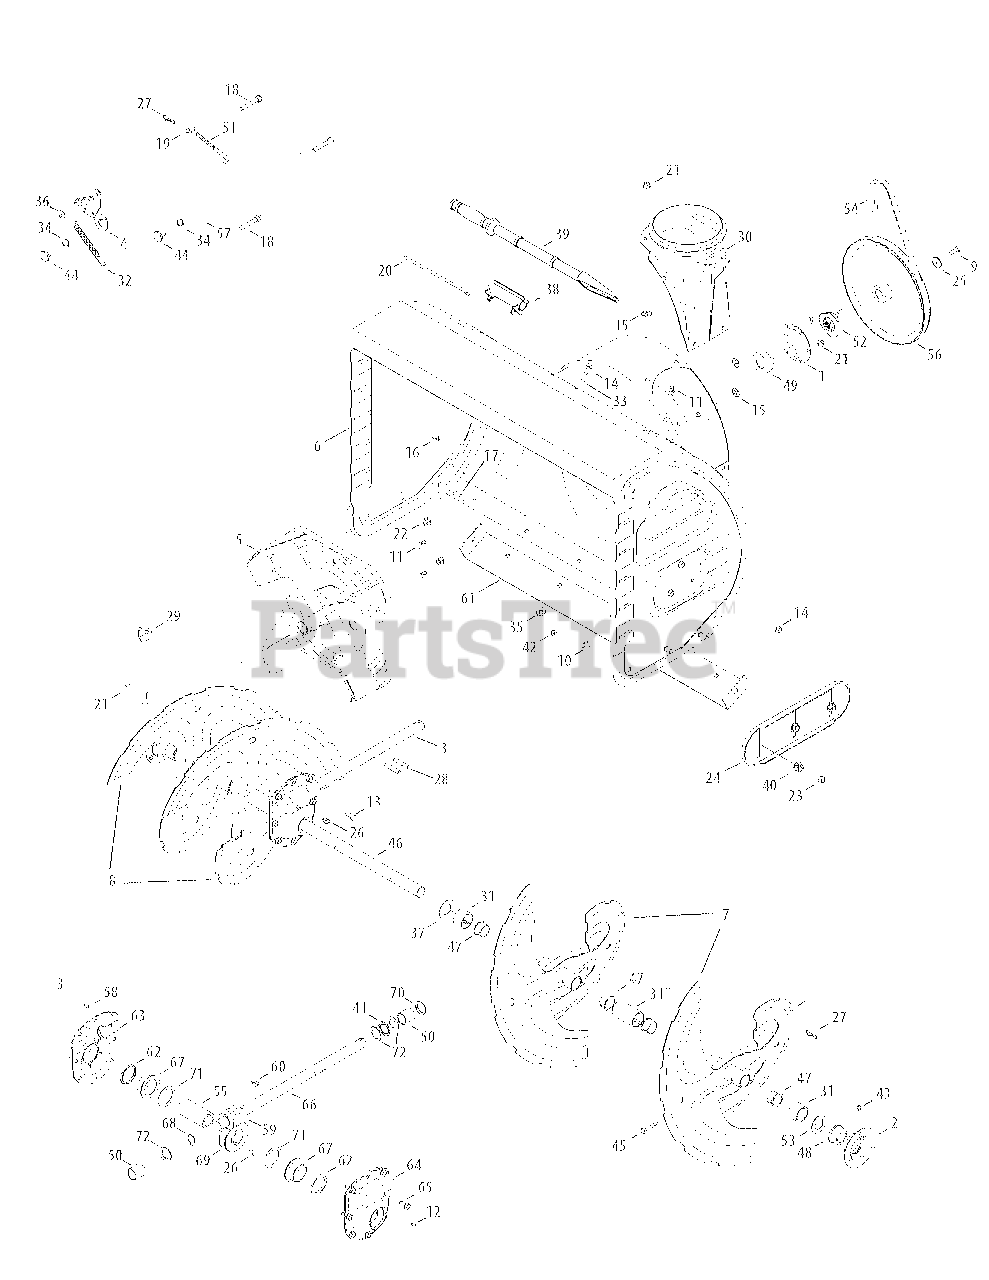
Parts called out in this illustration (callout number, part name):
1	Housing, Bearing
3	Gear Box Assembly
4	Bracket Assembly, Auger Brake
9	Screw, Hex Cap Lock, 5/16-24 x .875
10	Screw, Carriage, 3/8-16 x .75 Stainless
11	Screw, Carriage, 5/16-18 x .75
12	Fitting, Lube
13	Screw, Hex Cap, 5/16-18 x 1.0 Gr5
14	Screw, 5/16-18 x .750
16	Screw, Carriage, 5/16-18 x .75 Stainless
17	Screw, Carriage, 3/8-16 x 1.0 Stainless
18	Screw w/Stud, 5/16-18 x .4300
19	Ferrule
20	Tie Strap
21	Nut, Hex Flange Lock, 5/16-18
22	Nut, Hex Flange Lock, 3/8-16
23	Nut, Hex Lock, 3/8-16 Stainless
25	Washer, Flat, .34 x 1.5 x .15 Ht.
26	Key, Woodru, 1/4 x 3/4
27	Pin, Bow-tie Cotter
28	Pin, Spiral, 5/16 x 1.75
30	Adapter, Chute, 6"
31	Spacer, 1.0 x 1.5 x 1.0 Lg
31	Spacer, 1.0 x 1.5 x 2.5 Lg
32	Spring, Extension
33	Washer, Flat, .349 x .879 .063
34	Washer, Wave, .625 x .885 x .015
35	Washer, Bell., .34 x .872 x .06 Stainless
36	Washer, .344 x .75 x .12
37	Washer, 1.01 x 1.86 x .06
38	Clip, Mounting
39	Tool, Clean-out
40	Washer, Bell., .375 x .87 x .063 Stainless
41	Bearing, Thrust
42	Nut, Hex, 5/16-18 Stainless
43	Fitting, Lube
44	Screw, Shoulder, .625 x .17
45	Pin, Shear, .25 x 1.75
46	Shaft, Spiral
47	Bushing, Flange,
48	Bearing, Flange w/Flats
49	Bearing, Self Aligning
50	Sleeve
51	Rod, Auger Idler
52	Adapter, Pulley w/Pins
53	Spacer, 1.004 x 1.375 x .25
54	V-Belt, 1/2 x 42
55	Shaft, Gear, Worm
56	Pulley, Auger Drive, 10.0
57	Bracket, Auger Idler
59	Gear, Worm
60	Key, Hi Pro, 3/16 x 3/4
61	Plate, Shave, Stainless
62	Oil Seal
63	Hsg, Ass’y, Auger, RH
64	Hsg, Ass’y, Auger, LH
65	Screw, LD, 5/16-18 x .750
66	Shaft, Drive, Auger
67	Flange Bearing
68	External, Retaining, Ring
69	Gear, Worm, LH
70	Seal, Oil
71	Wash, Flat, 1.52ID x 2.0 OD
72	Wash, Flat, .88 ID x .38 OD
